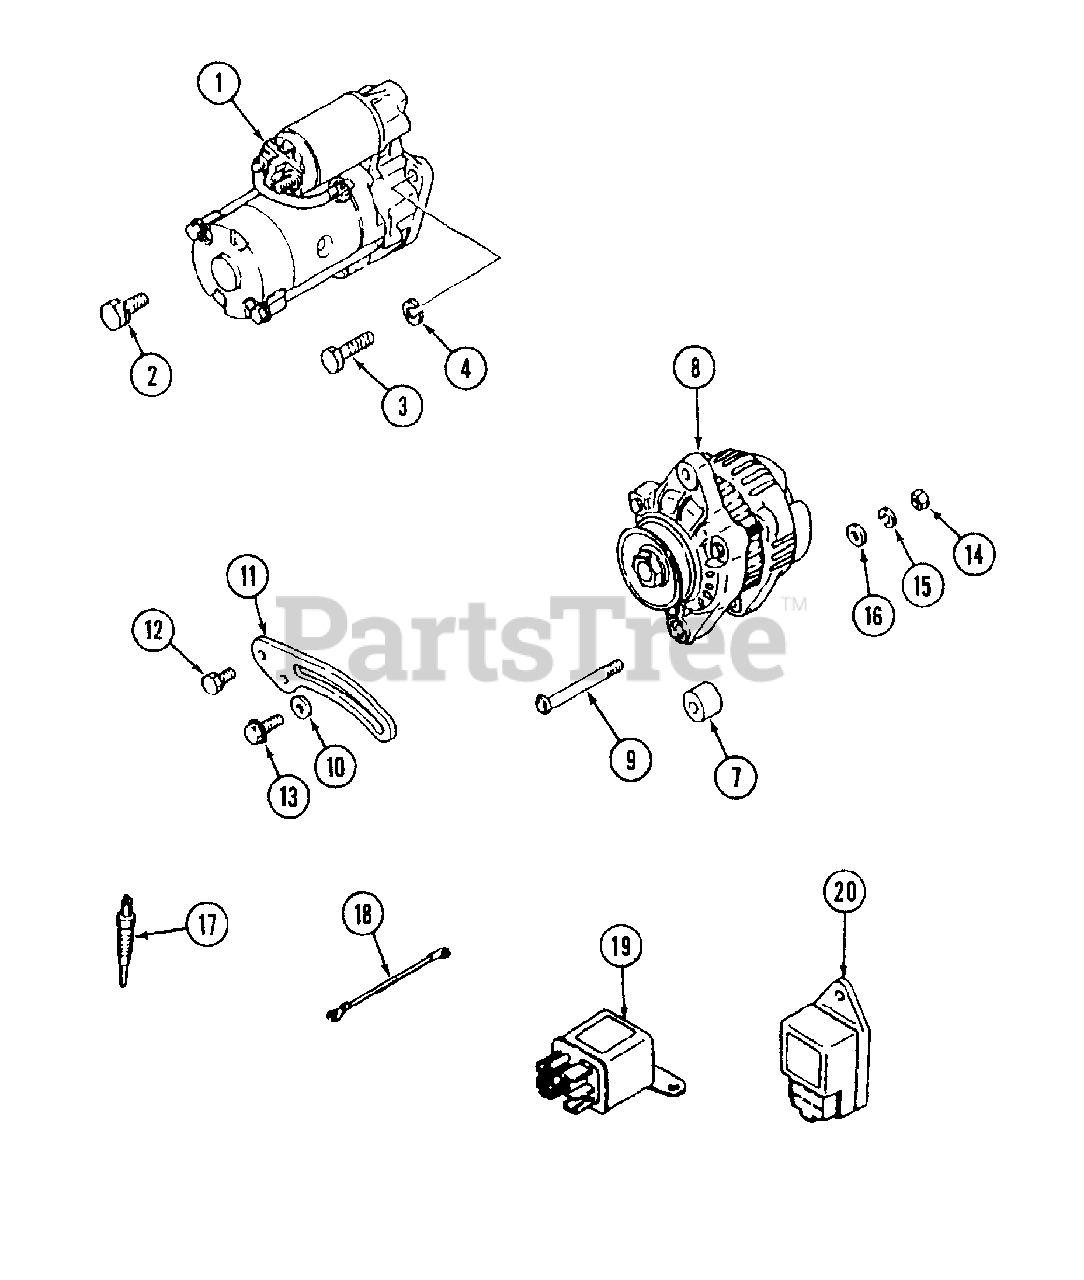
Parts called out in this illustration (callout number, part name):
1	Starter Ass'y.
2	Bolt, w/Washer
3	Bolt, Starter
4	Washer, Lock
8	Alternator Ass'y.
9	Bolt, Special
10	Washer, Plain
11	Brace, Generator
12	Bolt, w/Washer
13	Bolt, Flange
15	Washer, Spring
16	Washer, Plain
17	Plug, Glow
18	Wire, Glow Plug Lead
19	Relay, Glow
20	Timer, Glow
